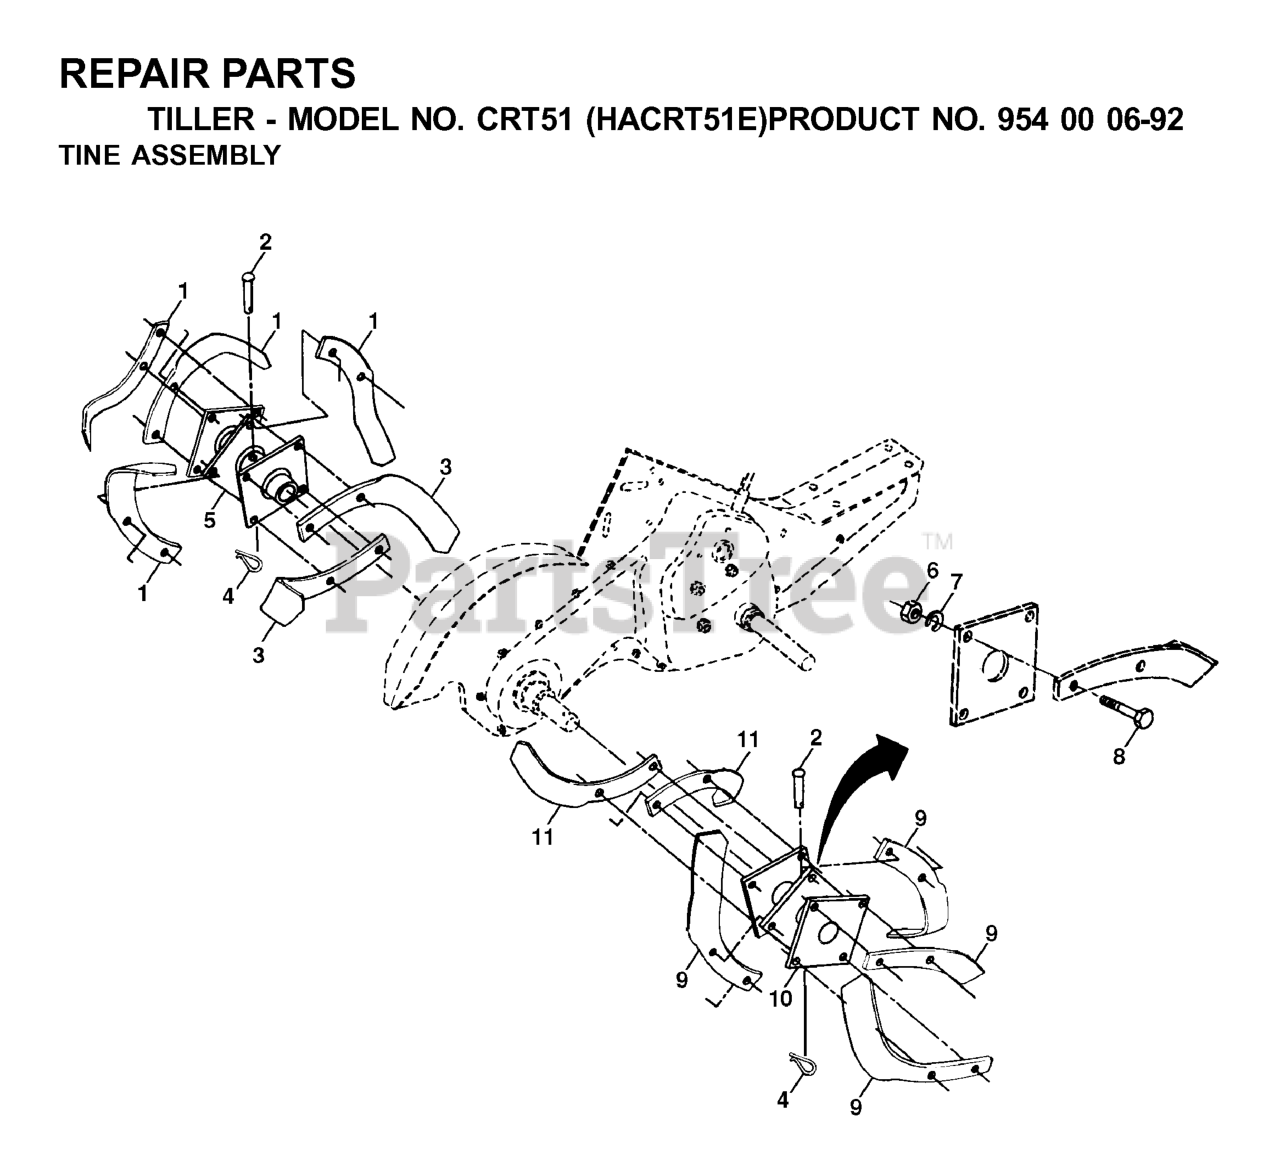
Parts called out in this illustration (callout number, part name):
1	TINE TI
2	PIN RETAINING SCREW
3	TINE.LH.12"(72L)
4	SPRING RETAINER
5	HUB.&.PLATE.ASM.LH
6	NUT
7	WASHER, LOCK 3/8
8	BOLT.HEX.001X20.37-24X1.ZINC
9	TINE TI
10	HUB & PLATE ASM RH
11	TINE.RH.12"(72R)
